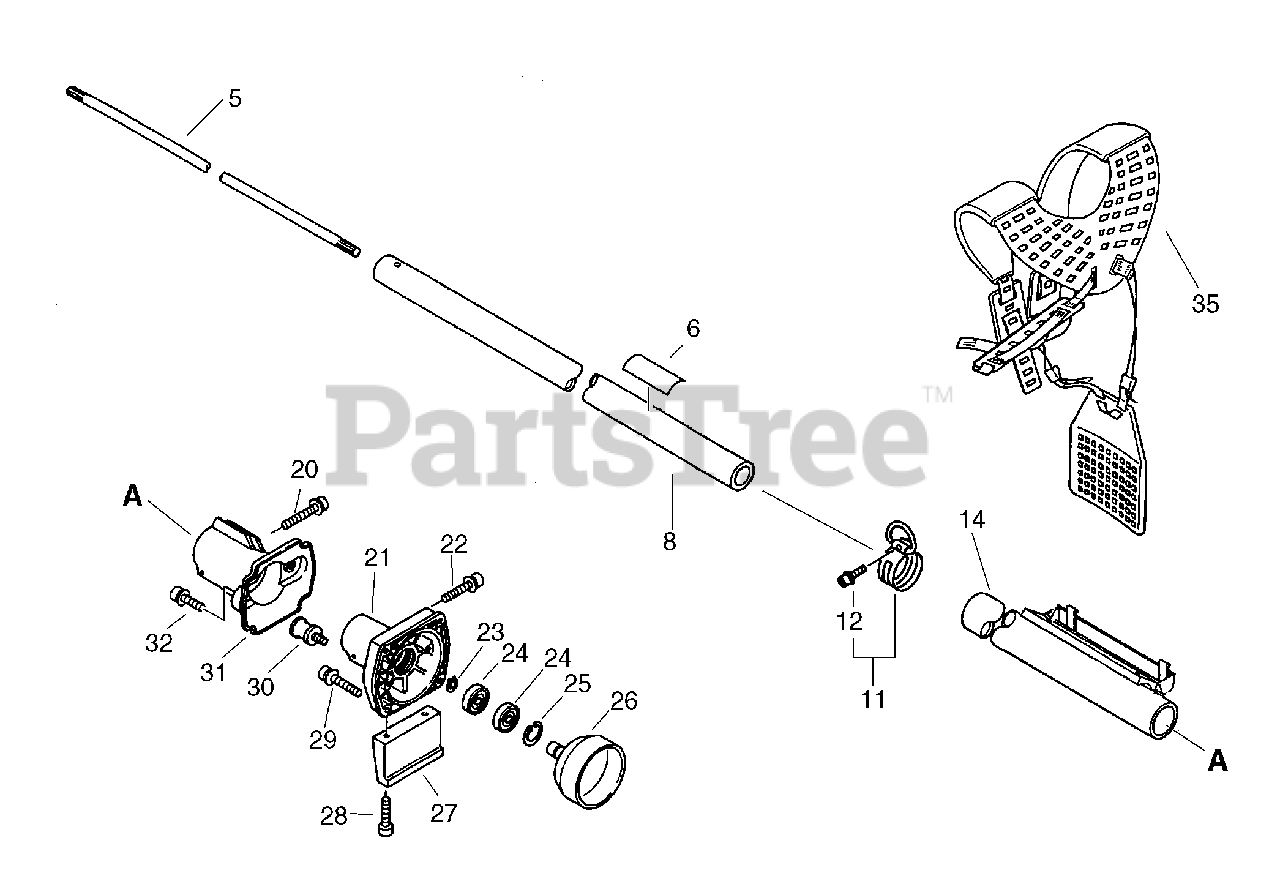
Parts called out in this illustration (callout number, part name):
5	DRIVESHAFT
6	LABEL - CAUTION
8	PIPE, MAIN
11	HANGER KIT
12	SCREW - 5X20
14	PIPE ASSY
20	SCREW - 5X35
22	SCREW - 5X30
23	RING, RETAINING - 15
24	BEARING, BALL - 6202
25	RING, RETAINING - 35
26	DRUM, CLUTCH
28	SCREW - 5X20
29	SCREW - 5X25
31	CLAMP, MAIN PIPE
32	SCREW - 5X14
35	HARNESS, SHOULDER
